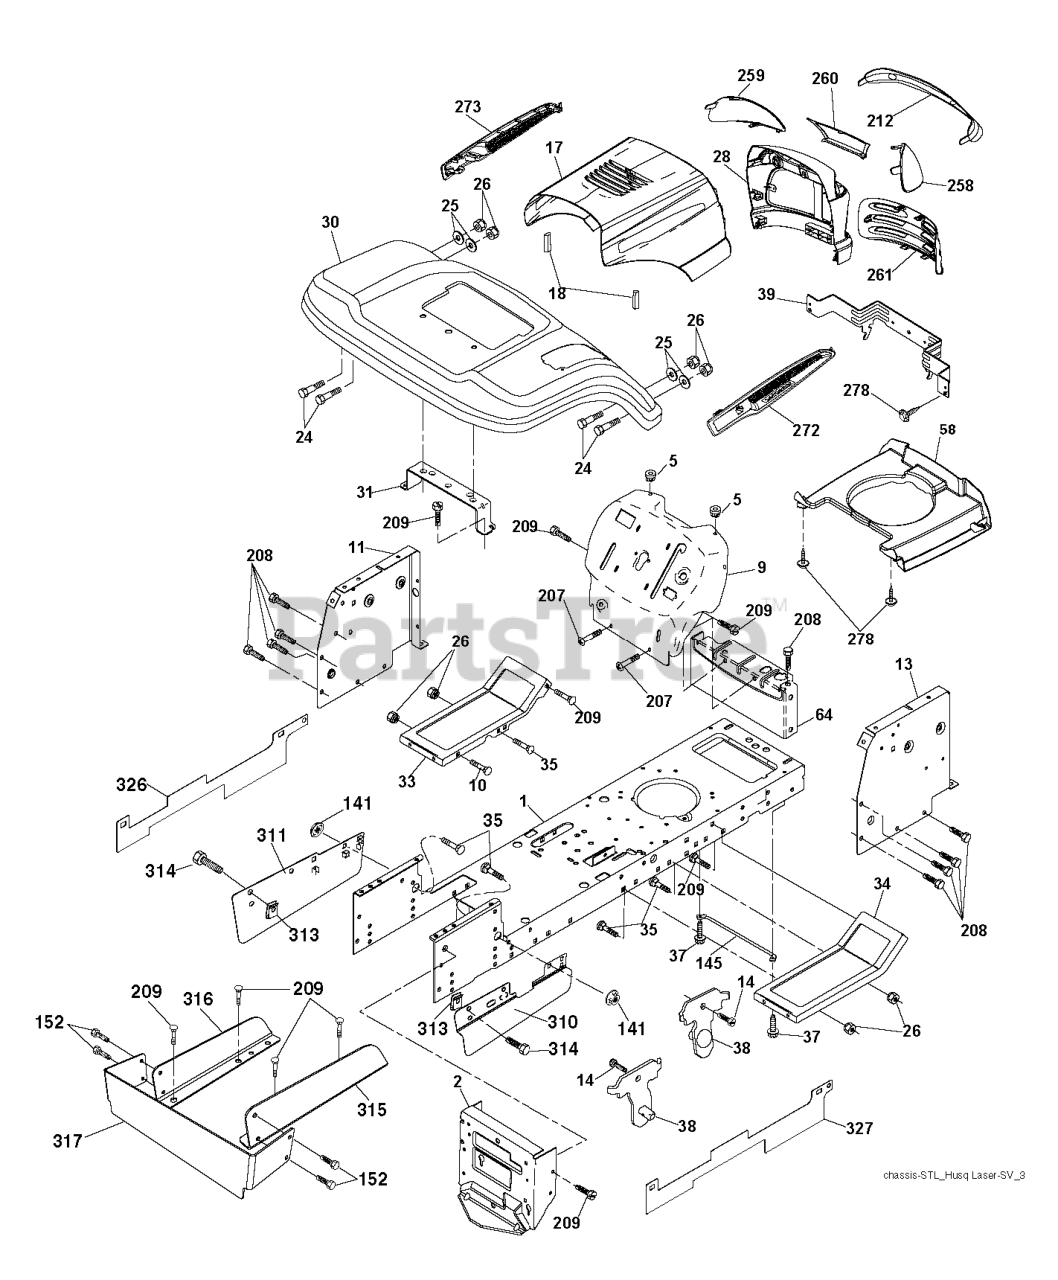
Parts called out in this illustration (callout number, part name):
1	CHASSIS STAMPING
2	DRAWBAR, 12GA
5	BUMPER.RUBBER.HOOD
9	DASH.SLKSCR.SL.PL.C.NA.NHMHUS
10	BOLT D
11	PANEL.DASH.LH.LTX
13	PANEL DASH RH
17	VENT.HOOD.LASER.III
18	BUMPER.HOOD.LARGE.1.75"
25	WASHER
26	NUT
30	FENDER.PNT.LTST.W/S.N/C.668ROS
31	BRACKET FENDER
33	FOOTREST.PNT.LH.BLACK
34	FOOTREST, RH
37	Screw 5/16-18 x 1/2 Hex, Self Tapping 5/16-18 x 1/2
38	BRACKET.ASM.PIVOT.MOWER.REAR
39	BRACKET PIVOT
64	DASH LOWER
141	NUT LOCK FLG 3/8-16 UNC
145	ROD.PIVOT.HOOD
152	SCREW
207	SCREW, 5/16-18 X 1/2
208	SCREW 3/8-16X1/2
209	SCREW, 3/8-16X3/4
212	INSERT.LENS.REFLECTIVE
258	LENS LH
259	LENS LH
260	COVER.LENS.HUSQ.LASER
272	VENT.HOOD.LASER.
273	VENT.HOOD.LASER.
278	SCREW.#10 X 0.750.BOS
314	SCREW.1/4-20X5/8
